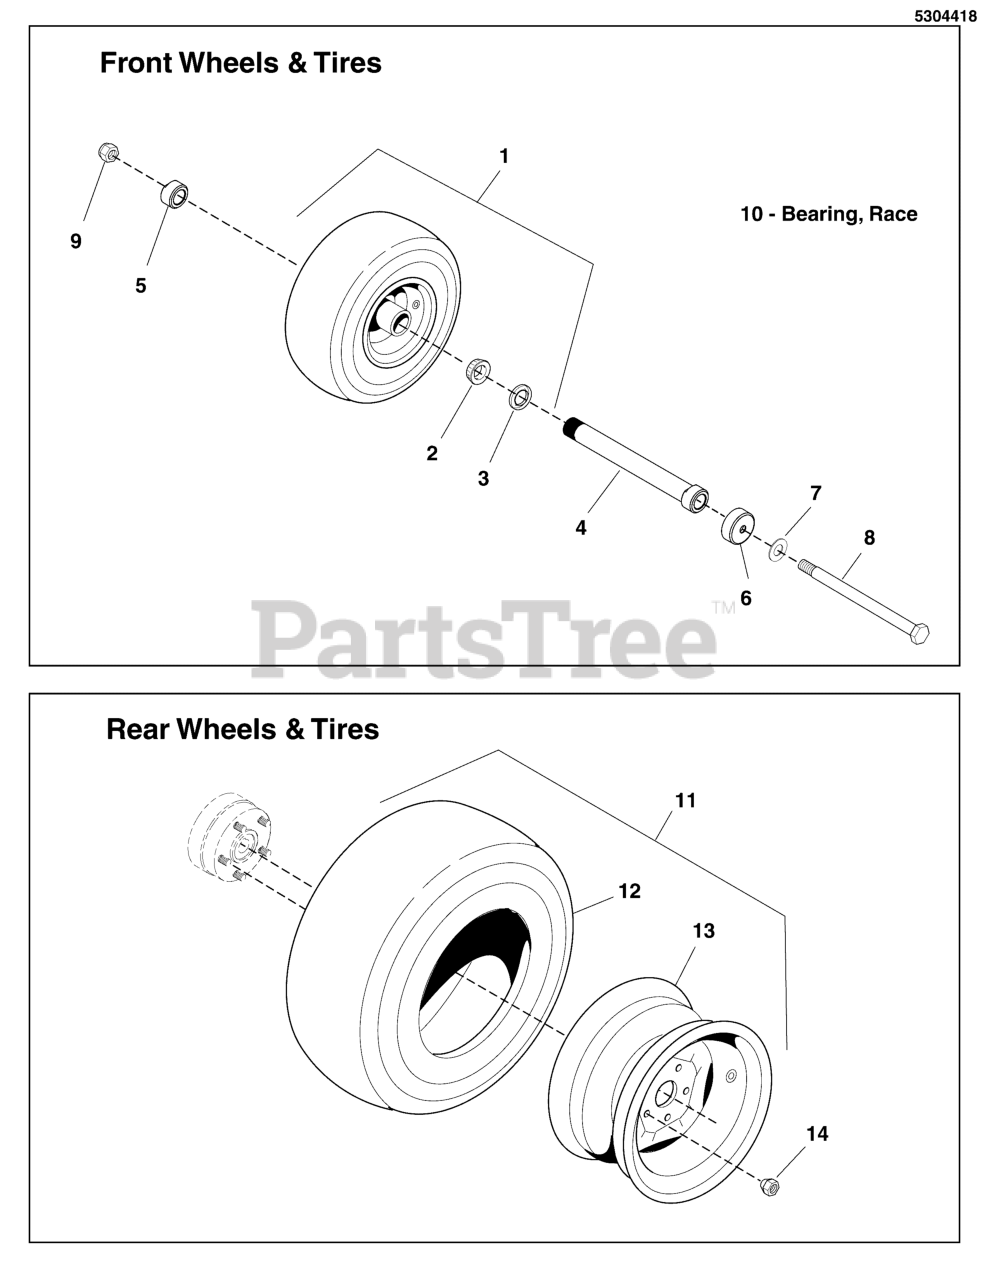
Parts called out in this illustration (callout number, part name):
1	TIRE ASSM, 13 X 6.5 - 6, FF / TB
2	BEARING, Tapered Roller
3	SEAL, GREASE
4	BEARING ADJUSTER, SPACER, 7.062 LG
5	NUT, BEARING ADJUSTER, AXLE
6	DEBRIS, COVER, CASTER WHEELS
7	WASHER, 1/2 SAE
8	BOLT, 1/2-13 X 9 GD5 CZ
9	NUT, Hex Flange, Nylock, 1/2-13
11	TIRE/WHEEL ASM, 26X12.00-12, TURF SMART
11	TIRE WHEEL ASM, 26X12.00-12, MULTI-TRAC
12	TIRE, TURF SMART, 26X12.00-12 4 PLY (SV)
12	TIRE, 26 X 12 - 12
13	WHEEL, 12 X 9.5, SOLD, 4.063" OFFSET (SV)
14	NUT, 1/2-20, FOR WHEEL BOLT SILVER
